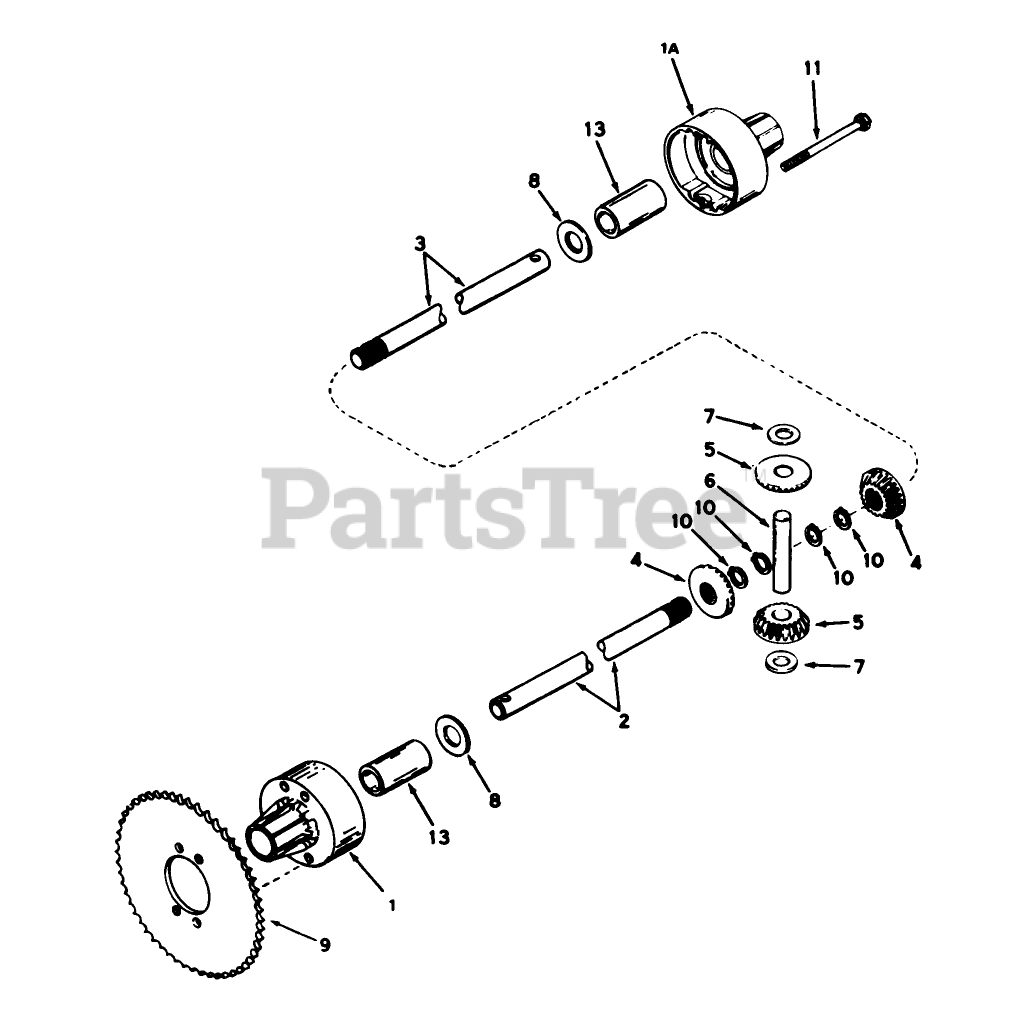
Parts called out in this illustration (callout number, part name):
1	Housing, Differential Carrier (Incl. Ref. #13)
1A	Housing, Differential Carrier (Incl. Ref. #13)
2	Axle (10-1/4" long)
3	Axle (18-7/8" long)
4	Gear Bevel
5	Gear Pinion
6	Pin Drive
7	Washer Thrust
8	Washer
9	Sprocket (See "Sprocket Chart" for optional sprocket)
10	Retaining Ring (pkg of 2)
11	Screw-Hex Hd.
13	Bushing
